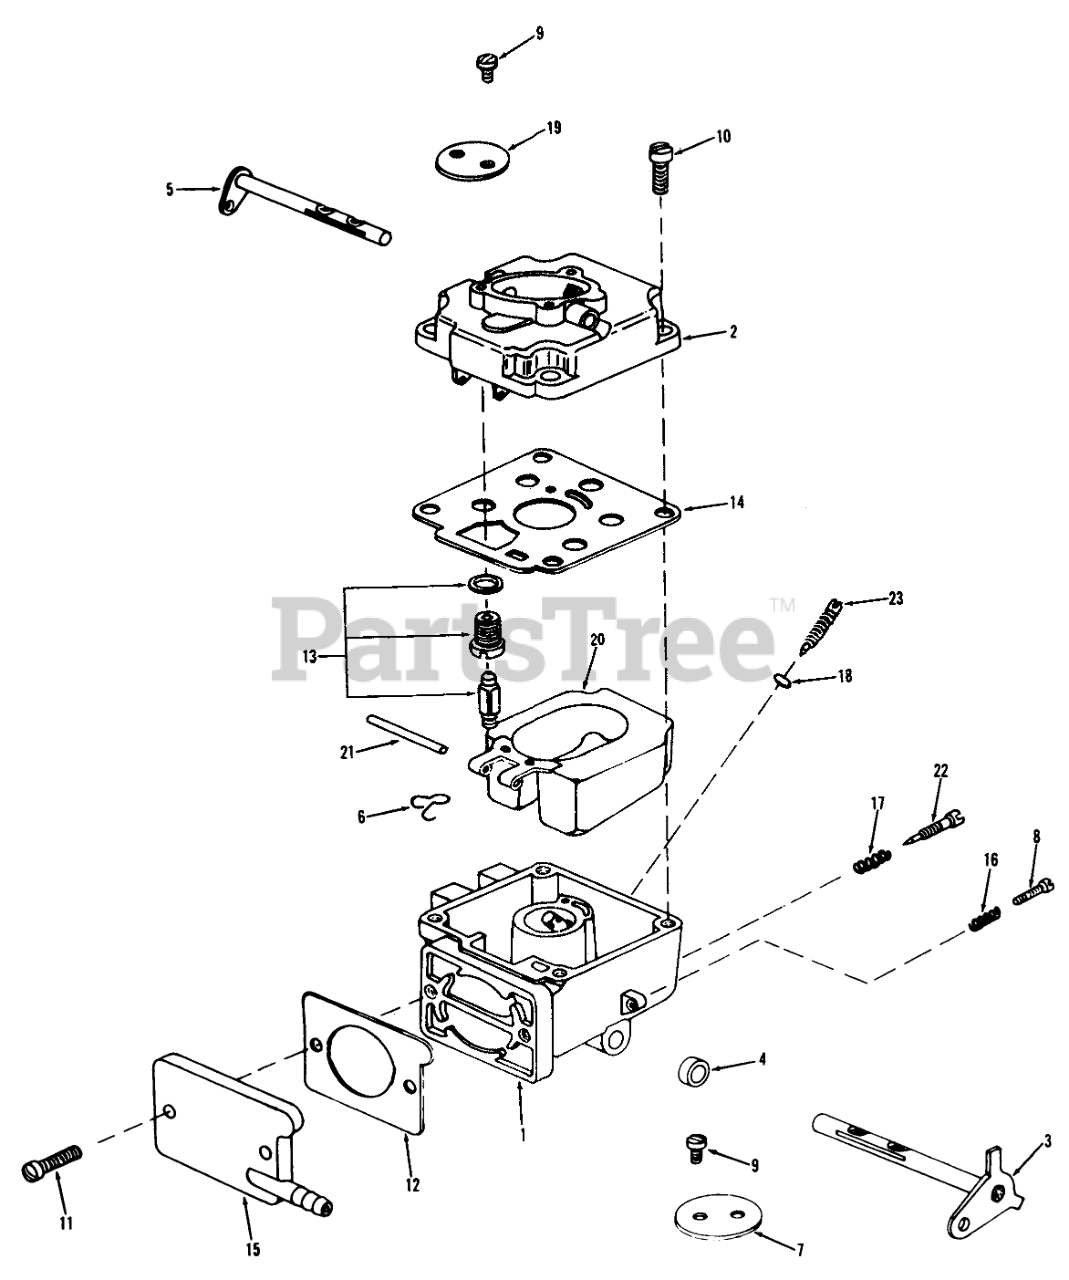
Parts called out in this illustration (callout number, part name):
1	Lower Body Assy
2	Sleeve Assy
3	Shaft-Throttle
4	Packing Shaft
5	SHAFT-CHOKE
6	CLIP-FLOAT VALVE
7	Throttle Fly
8	Screw-Throttle Stop
9	Screw-Fly Mounting
10	SCREW-BOWL COVER MTG
11	Screw-Inlet Plate
12	Gasket-Plate
13	Float Valve Assy
14	GASKET
15	Carburetor Inlet Plate
16	Spring-Throttle Stop
17	Spring-Idle Needle
18	GASKET-O RING
19	Choke Fly
20	Float & Lever Assy
21	Shaft,Float Lever
22	Idle Needle
23	High Speed Needle
